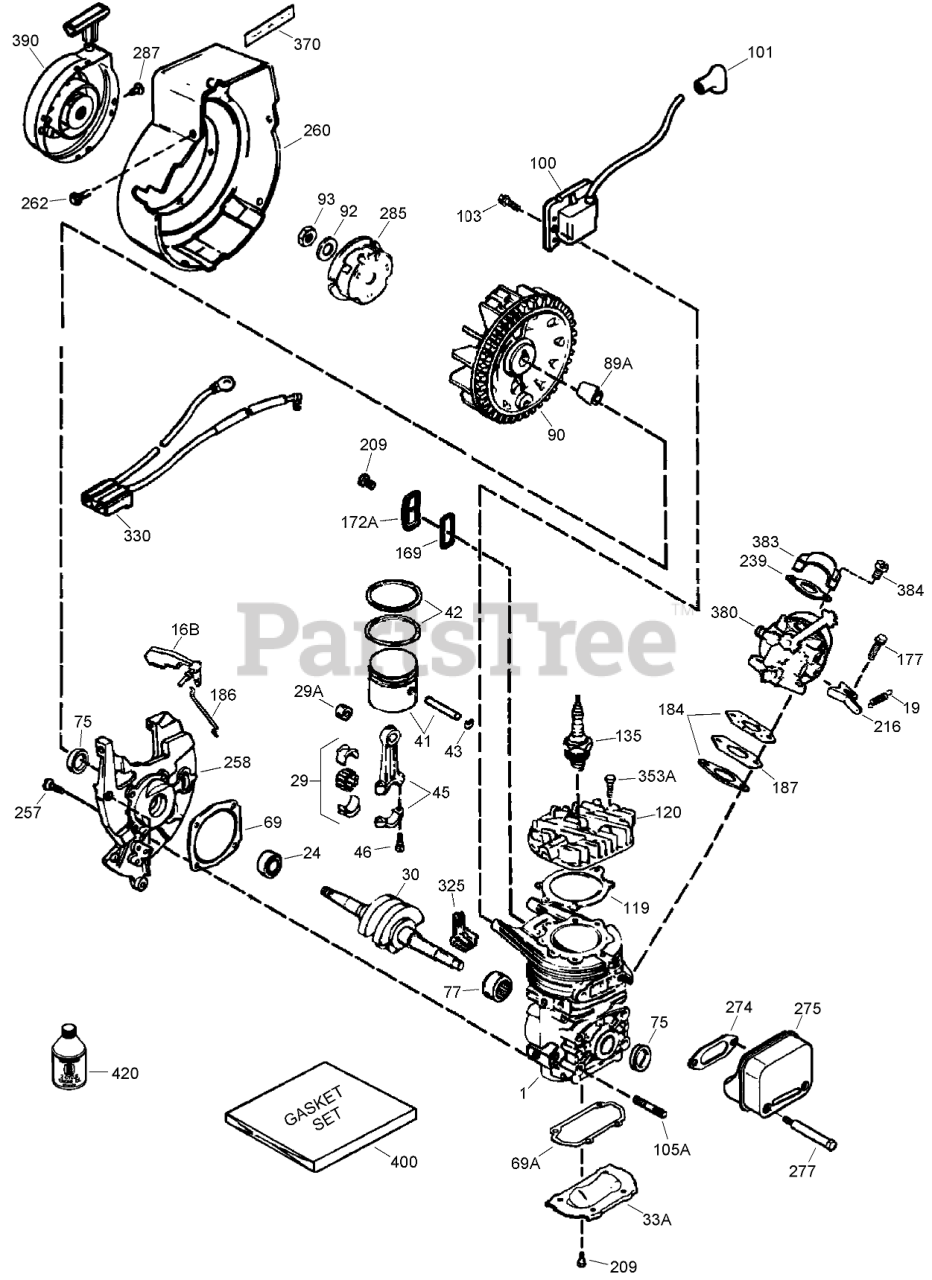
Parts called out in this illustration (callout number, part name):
1	Short Block-Replacement
16B	Vane-Air
19	Spring-Extention (Governor)
24	Bearing-Ball
29	Needle Bearing and Liner Set (37 Needle)
29A	Bearing-Cartridge
30	Crankshaft
33A	Plate-Cover
41	Piston and Pin Asm
42	Ring Set
43	Ring-Retaning (Piston Pin)
45	Connecting Rod Asm (Includes 29)
46	Bolt-Rod, Connecting
69	Gasket-Cover, Cylinder
75	Seal-Oil
77	Bearing-Cartridge
89A	Sleeve-Adapter
90	Flywheel
92	Washer-Belleville
93	Nut-Flywheel
100	Ignition-State, Solid
101	Cover-Spark Plug
103	Screw (T-15, 10-24 x 15/16)
105A	Stud
119	Gasket-Head, Cylinder
120	Head-Cylinder
135	Spark Plug-Resistor (R C J 8Y)
169	Gasket-Plate, Cover
172A	Cover-Release, Compression
177	Screw (5/32 Allen, 1/4-20 x 1)
184	Gasket-Carburetor
186	Governor-Link
187	Spacer
209	Screw (T-25, 10-24 x 1/2)
216	Lever-Adjusting, Rpm
239	Gasket-Cleaner, Air
257	Screw (T-30, 1/4-20 x 5/8)
258	Base-Housing, Blower
260	Housing-Blower
262	Screw (1/4-20 x 1/2)
274	Gasket-Exhaust
275	Muffler (Includes 274, 277)
277	Screw (1/4-20 x 2-3/4)
285	Cup-Starter
287	Screw (8-32 x 21/64)
325	Clip-Wire
330	Harness-Wire
353A	Screw (T-30, 1/4-20 x 3/4)
370	Decal-Tecumseh Logo for Top of Recoil Starter
380	Carburetor (Includes 184)
383	Baffle-Carburetor
384	Screw (T-25, 10-32 x 5/8)
390	Starter-Rewind
400	Gasket Set
420	Oil-2 Cycle (8 Oz)
